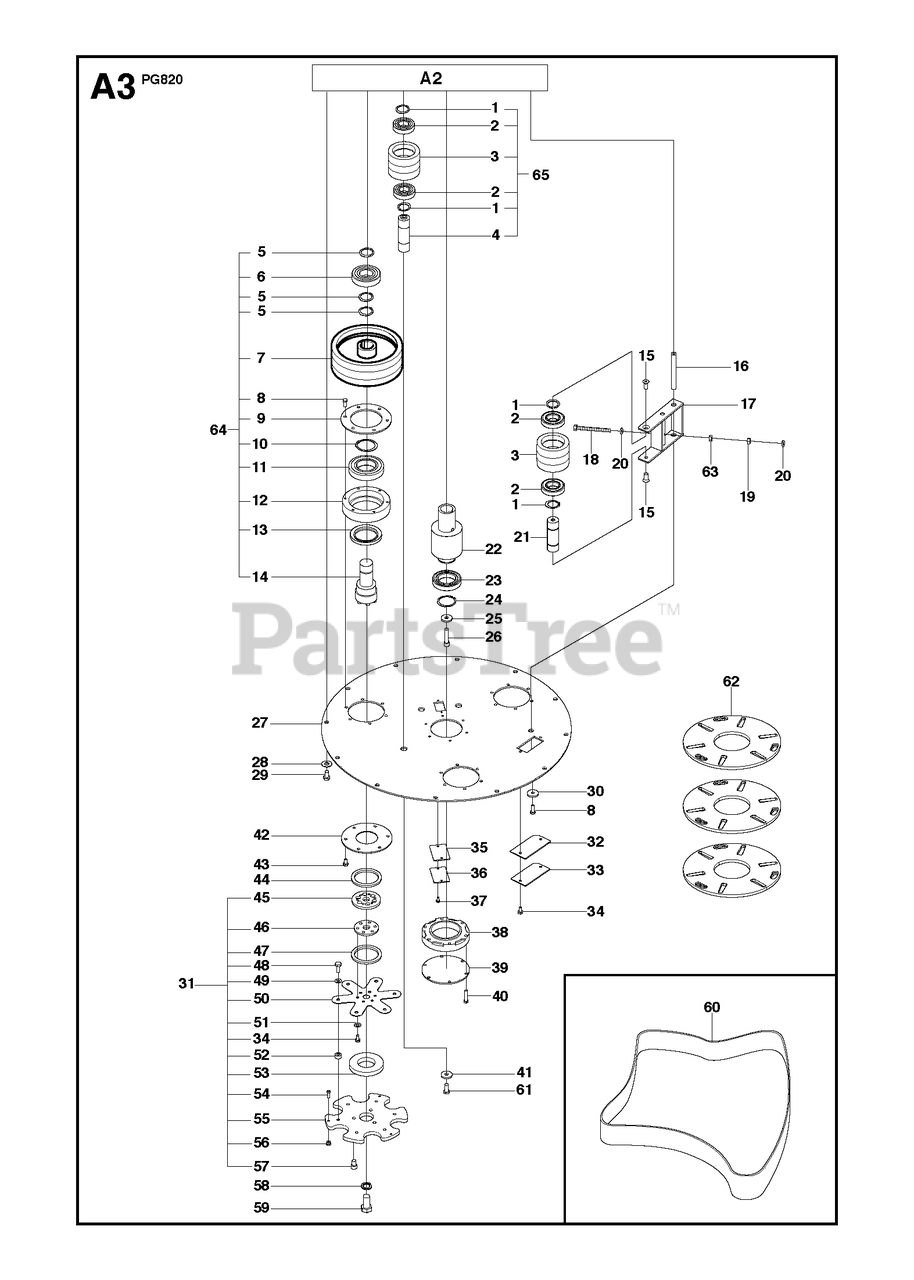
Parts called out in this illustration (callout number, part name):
20	WASHER
28	WASHER
34	SCREW EHHM
49	WASHER
51	WASHER
63	HEXAGON LOCKING NUT
